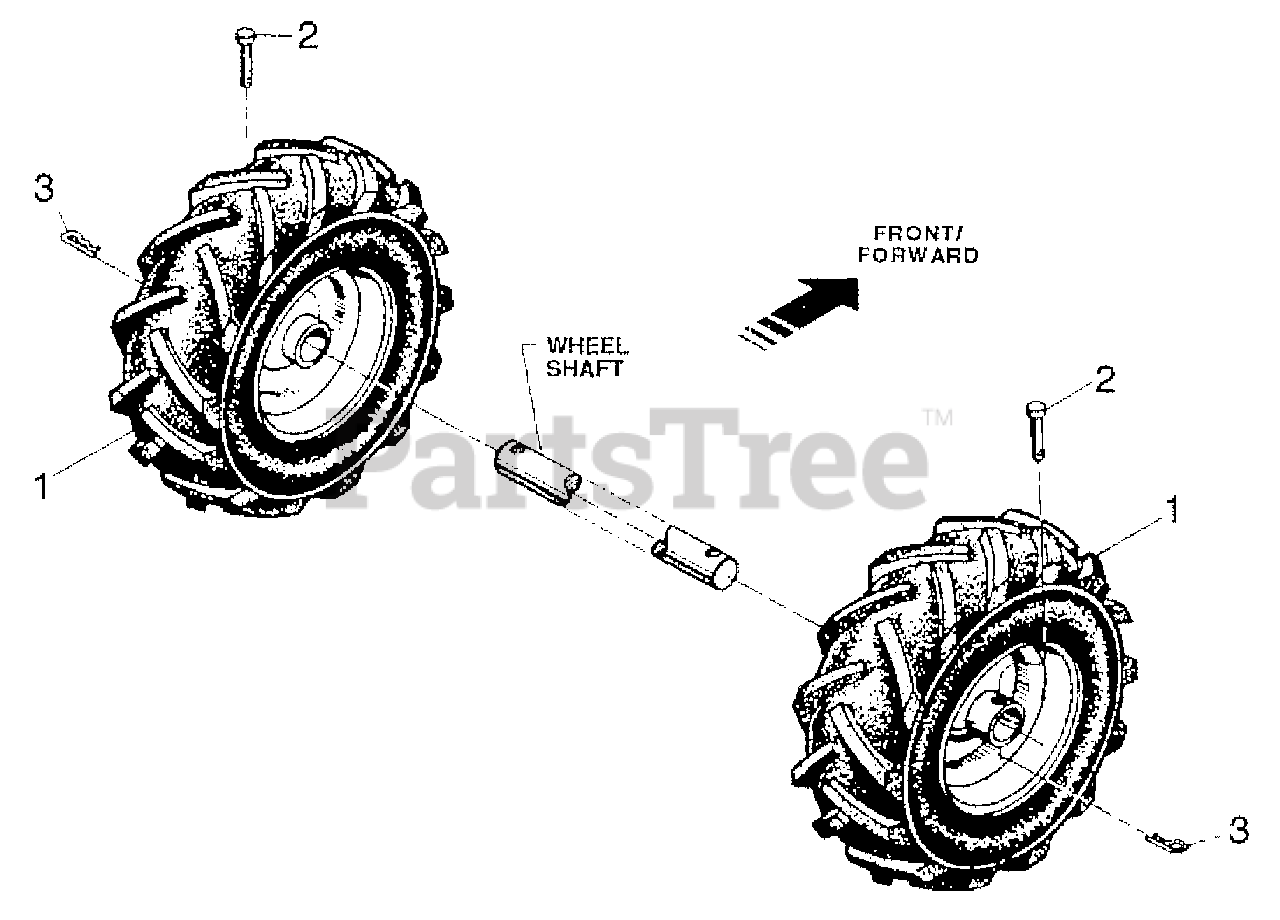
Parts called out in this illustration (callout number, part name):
1	Wheel & Tire Assembly
2	Clevis Pin, .312 x 1-3/4
3	Hair Pin Cotter
